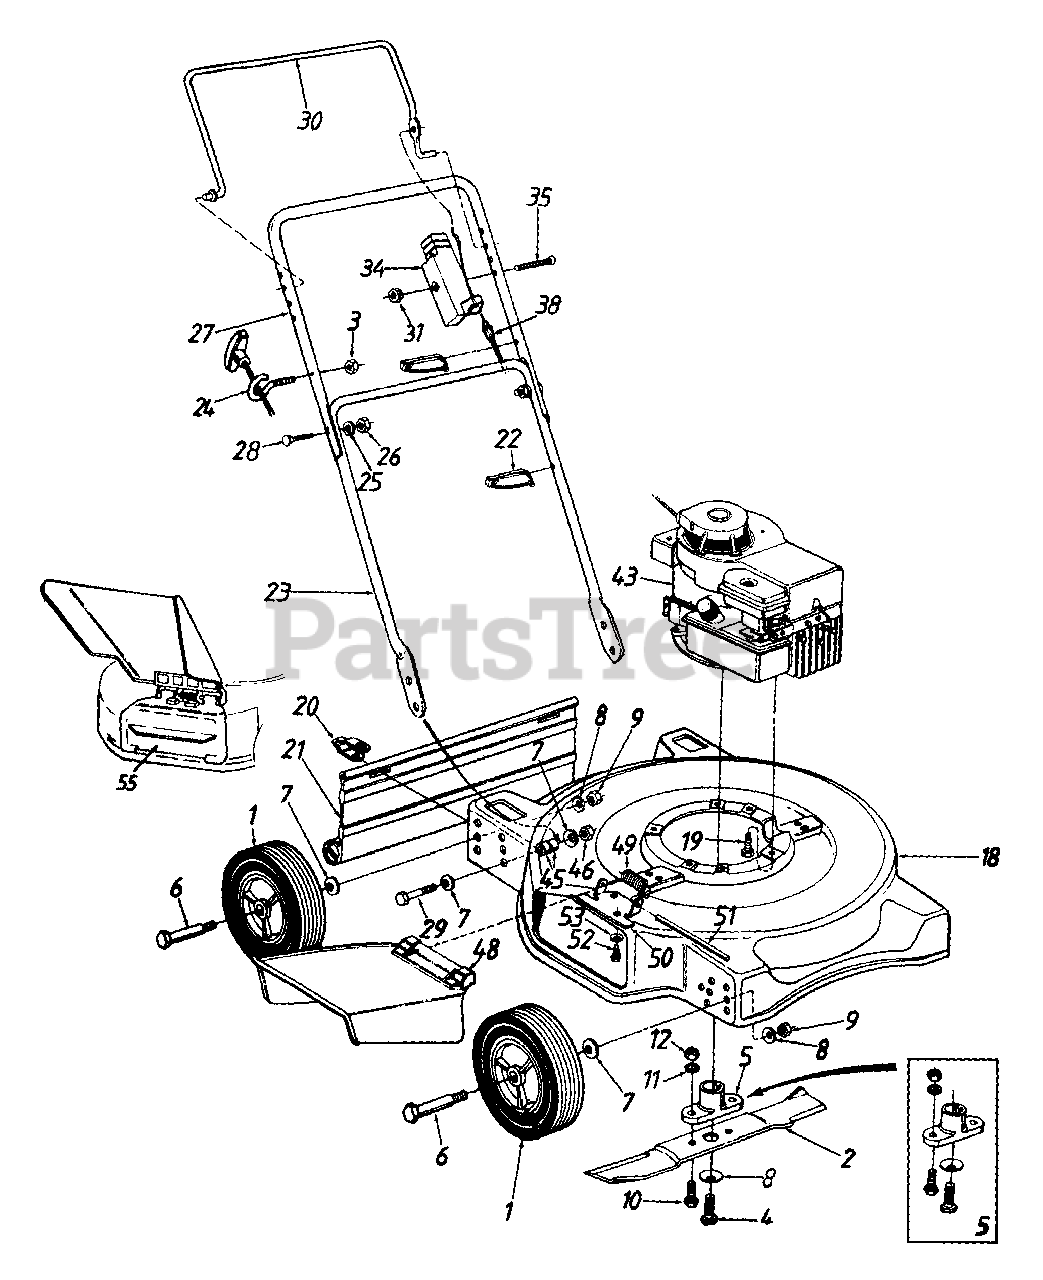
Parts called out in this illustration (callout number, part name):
1	Wheel Ass'y. Comp.
2	20" Blade
3	Hex L-Nut 1/4-20 Thd.
4	Hex Bolt 3/8-24 x 1.5" Lg.
5	Blade Adapter Kit (Keyed)
7	Bell-Wash. .380" I.D. x .88"
8	Bell-Wash. .39" I.D. x 1.13"
9	Hex Nut 3/8-16 Thd.
10	Hex Bolt 3/8-24 x 1" Lg.
11	L-Wash. 3/8" I.D.
12	Hex Nut 3/8-24 Thd.
18	20" Deck Ass'y.
19	Hex Wash. Hd. Scr. 3/8-16 x 1" Lg.
20	Hinge Clip
21	Rear Flap
22	Cable Tie
25	L-Wash. 5/16" I.D.
26	Hex Nut 5/16-18 Thd.
29	Hex Bolt 3/8-24 x 1.5" Lg.
31	Hex L-Nut 1/4-20 Thd.
34	Throttle Body
35	Oval C-Sunk Scr.
38	Control Cable
43	Engine
45	Spacer .391" I.D. x .375" Lg.
46	Hex L-Nut 3/8-24 Thd.
48	Chute Deflector Ass'y.
49	Torsion Spring
50	Adapter Plate
51	Hinge Pin
52	Hex Self-Tap Scr. 1/4-20 x .5"
53	Bell-Wash. 1/4" I.D.
55	Mulching Plug
